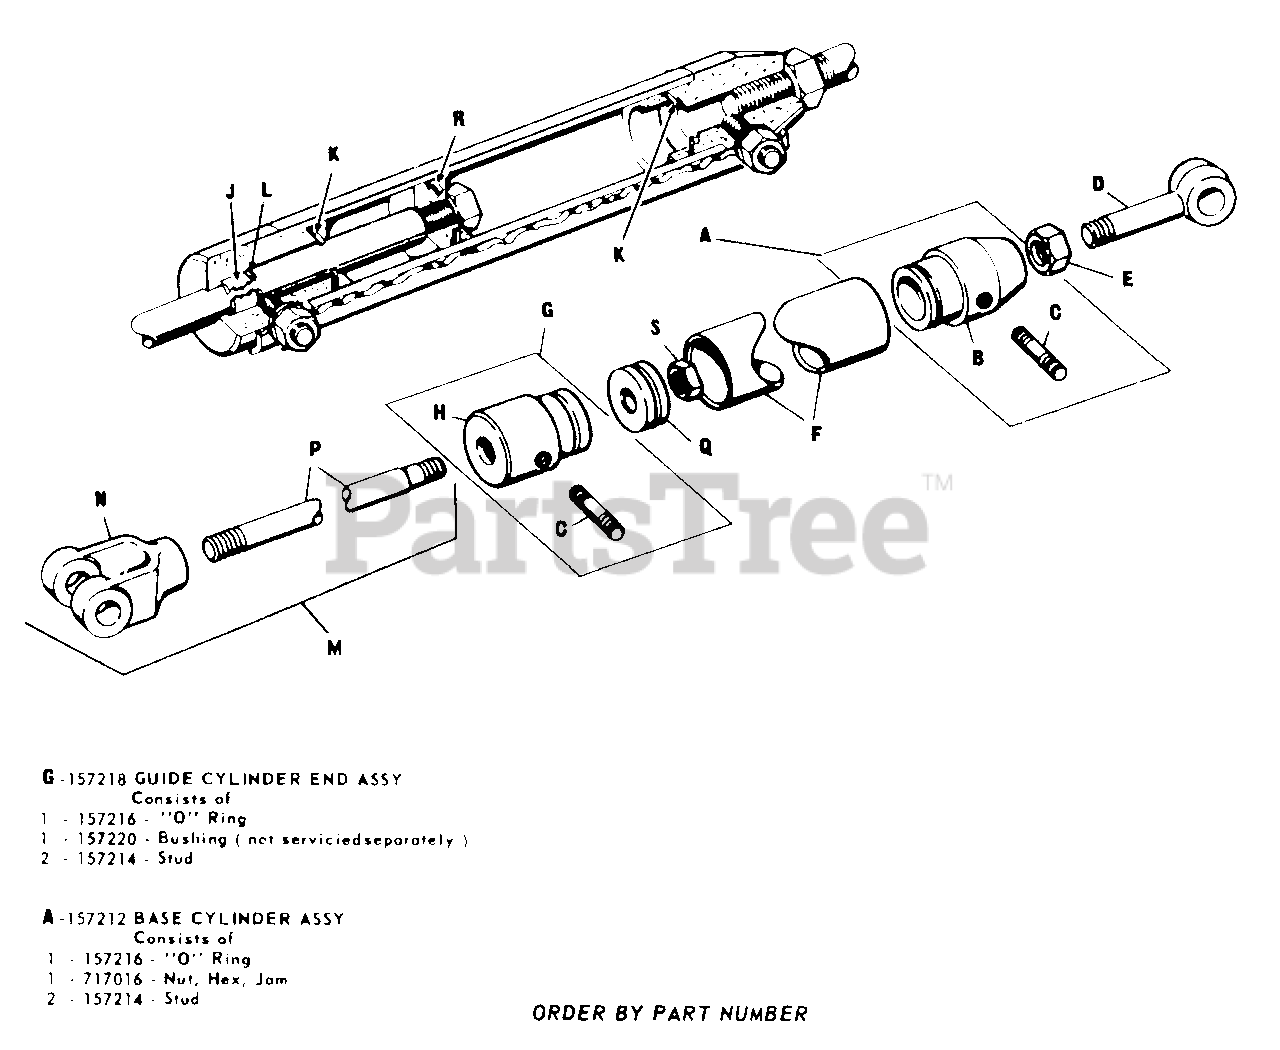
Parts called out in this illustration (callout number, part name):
A	Cylinder Base Sub-Assembly-Consists of:
A	"O" Ring
A	Nut, Hex, Jam
A	Stud
B	Cylinder Base
C	Stud Bolt, 5/16"-18 x 7/8"
E	Jam Hex. Nut, 1/2"-20
G	Sub Assembly Guide-Consists of:
G	"O" Ring
G	Bushing (not serviced separately)
G	Stud
H	Cylinder End Guide
M	Yoke & Rod Sub-Assembly
P	Piston Rod
R	"O" ' Ring
S	Full Hex. Nut
